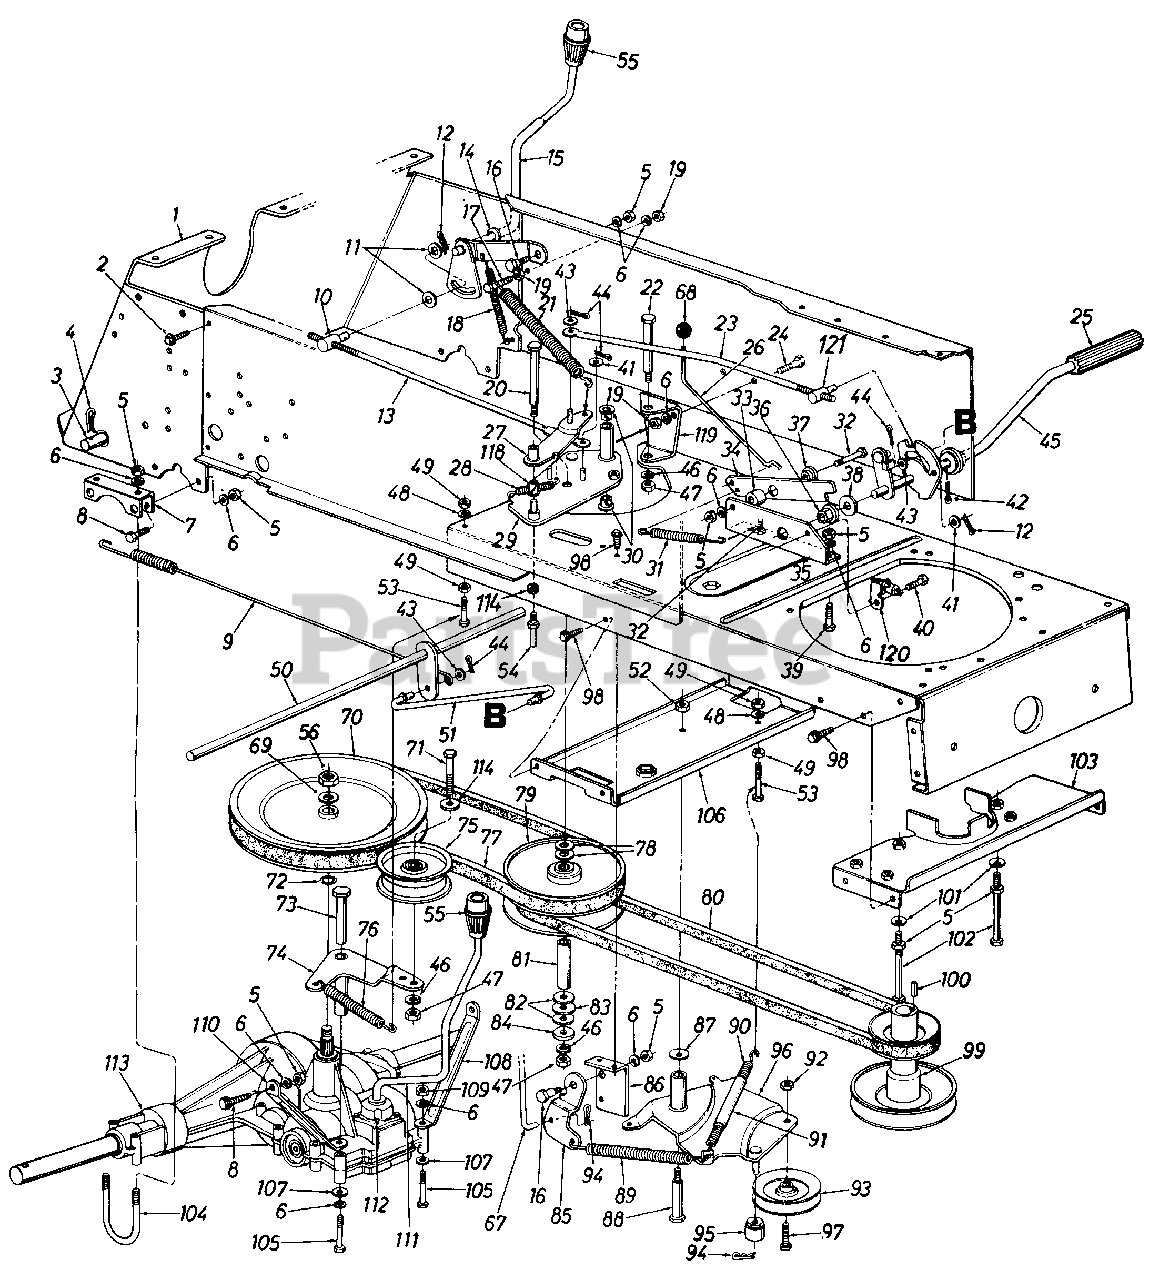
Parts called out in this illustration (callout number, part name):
3	Hitch Rod
4	Hitch Pin Clip
5	Hex Nut 5/16-18 Thd.
6	L-Wash. 5/16" I.D.*
7	Transaxle Bracket
8	Hex Bolt 5/16-18 x .75" Lg. (Grade 5)
9	Brake Extension Spring
10	Adjustment Ferrule 3/8-24 Thd.
11	Fl-Wash. .385" I.D. x .87"
12	Internal Cotter Pin
13	Speed Control Link
14	Fl-Wash. .531" I.D. x .94"
15	Speed Selector Lever Ass'y.
16	Shld. Bolt .437" Dia. x .162"
17	Hex Bolt 5/16-24 x 1.25" Lg.
18	Extension Spring 3.9" Lg.
19	Hex Nut 5/16-24 Thd. (Grade 5)
20	Hex Bolt 3/8-24 x 4.5" Lg.
21	Extension Spring 11" Lg.
22	Shld. Bolt .625" Dia. x 3.5" Lg.
23	Speed Control Link
24	Hex Bolt 5/16-24 x .75" Lg.
25	Foot Pad
26	Parking Brake Link
27	Variable Speed Torque Brkt. Ass'y.
28	Extension Spring 2.59" Lg.
29	Pulley Brkt. Sub Ass'y.
30	Flanged Brg. .625" I.D.
31	Extension Spring 2.51" Lg.
32	Hex Bolt 5/16-18 x 1.25" Lg.
33	Spacer .34" I.D. x .88"
36	Hex Flange Brg. .634" I.D.
37	Shld. Spacer .5" Dia.
38	Fl-Wash. .64" I.D. x 1.24"
39	Hex Bolt 5/16-18 x .75" Lg.
40	Hex Tap Scr. #10-32 x 5/8 Lg.
41	Fl-Wash. .406" I.D. x .75" O.D.
42	Cotter Pin 118" Dia.
43	Fl-Wash. .34" I.D. x .68" O.D.
44	Cotter Pin 3/32" Dia.
45	N Foot Pedal Brkt. Ass'y.
46	L-Wash. 3/8" I.D.
47	Hex Nut 3/8-24 Thd.
48	L-Wash. 1/4" I.D.
49	Hex Nut 1/4-20 Thd.
50	Brake Link Bracket
51	Front Brake Rod Link
52	Hex Cent. L-Nut 3/8-16 Thd.
53	Hex Bolt 1/4-20 x 2.0" Lg.
54	Belt Guard Pin
55	Shift Knob
56	Hex Jam Nut 9/16-18 Thd.
67	Deck Control Rod
68	Ball Knob Brake
69	Bell-Wash. 9/16" I.D. x 1.25"
70	V-Pulley 1/4" O.D.
71	Hex Bolt 3/8-24 x 1.75" Lg.
72	Wire Ring
73	Shld. Bolt 5/16-24 Thd.
74	Idler Brkt. Ass'y.
75	Flat Idler 3.5" O.D.
76	Extension Spring 6.12" Lg.
77	V-Belt
78	Teflon Washer 1.20" O.D.
79	Variable Speed Pulley 6" Dia.
80	V-Belt
81	Pivot Bushing
82	Fl-Wash. .56" I.D. x 1.0" O.D.
83	Thrust Brg. .56" I.D. x 1.25"
84	Retainer Cup
85	Deck Control Pivot Brkt.
86	Parking Brake Mtg. Brkt.
87	Bell-Wash. .38" I.D. x .88" O.D.
88	Shld. Bolt .498" Dia. x 2.05"
89	Extension Spring 6.12" Lg.
90	Extension Spring 6.37" Lg.
91	Convoluted Conduit 4" Lg.
92	Hex Cent. L-Nut 3/8-24 Thd.
93	V-Belt Idler
94	Internal Cotter Pin
95	Spacer
96	Idler Brkt. Deck Ass'y.
97	Hex Bolt 3/8-24 x 1.5" Lg.
98	Hex TT-Tap Scr. 1/4-20 x .5"
99	Engine Pulley
100	Sq. Key 1/4 x 1.5" Lg.
101	Bell-Wash. .345" I.D. x .88"
102	Hex Bolt 5/16-18 x 5.25" Lg.
103	Belt Keeper Brkt. Ass'y.
104	U-Bolt
105	Hex Bolt 5/16-24 x 2.25" Lg.
106	Deck Idler Support Brkt.
107	Fl-Wash. .344" I.D. x .62" O.D.
108	Front Trans. Support Brkt. L.H.
109	Hex Nut 5/16-24 Thd.
110	Front Trans. Support Brkt. R.H.
111	Shift Lever Ass'y. Complete
112	Socket Hd. Cap Scr. #10 x 24
113	2-Speed Transmission Comp.
114	Fl-Wash. 3/8" I.D. x 1.0" O.D.
118	Nyliner Flanged Brg.
119	Variable Speed Support Brkt.
120	N Safety Switch
121	Adjustment Ferrule 3/8-24 Thd.
